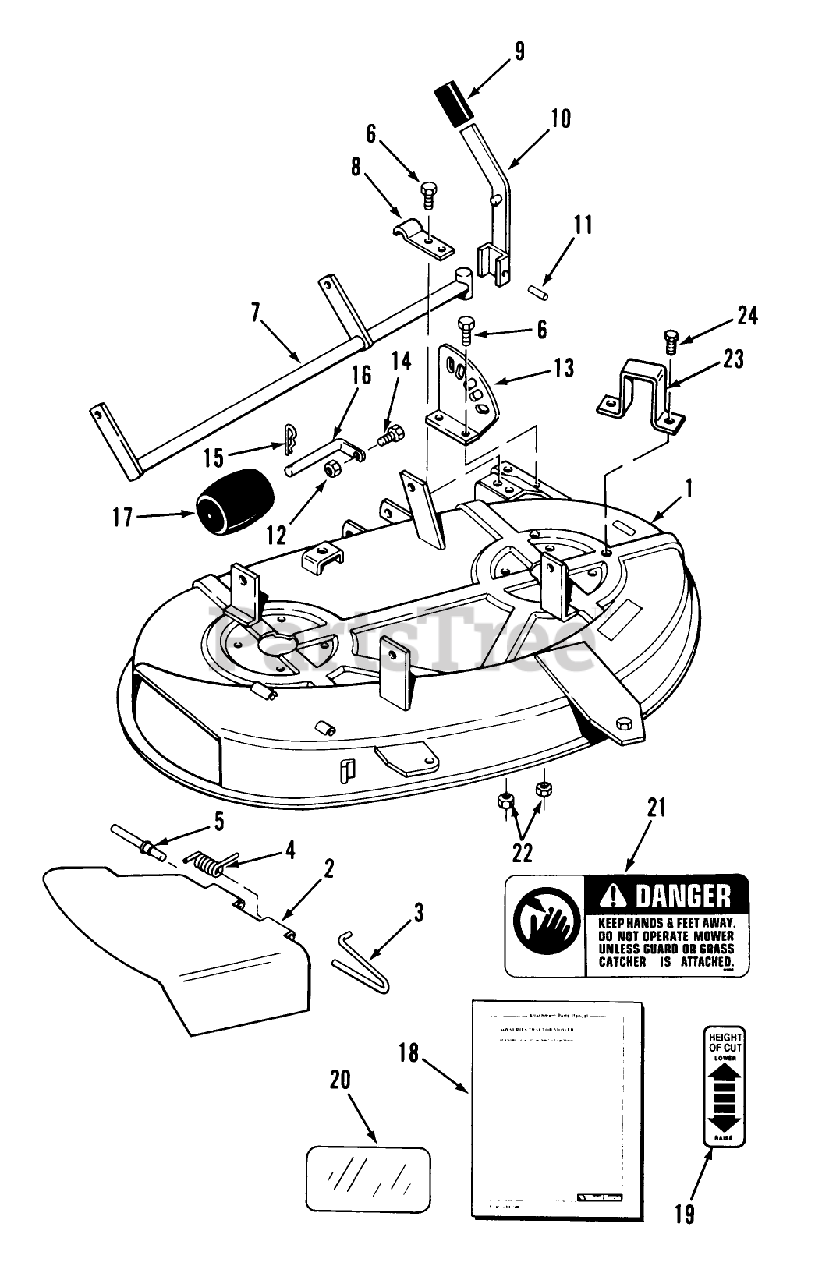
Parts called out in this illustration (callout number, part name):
1	V-BELT
2	Spindle Wrench
3	Decal-Routing
4	Spindle
5	BEARING SPACER
6	RING-RETAINING
7	SPACER-SPINDLE
8	Nut
9	Bolt
10	Blade
11	Cup
12	NUT-LOCK NI
13	DECK PULLEY
14	SPINDLE SHAFT WA
15	Washer
16	BEARING-BALL
17	RETAINING RING
18	O RING
19	BEARING-BALL
20	PULLEY-COUNTER SHAFT
21	Zerk
22	NUT
23	Washer
24	Pulley
25	Bolt
26	V-BELT
